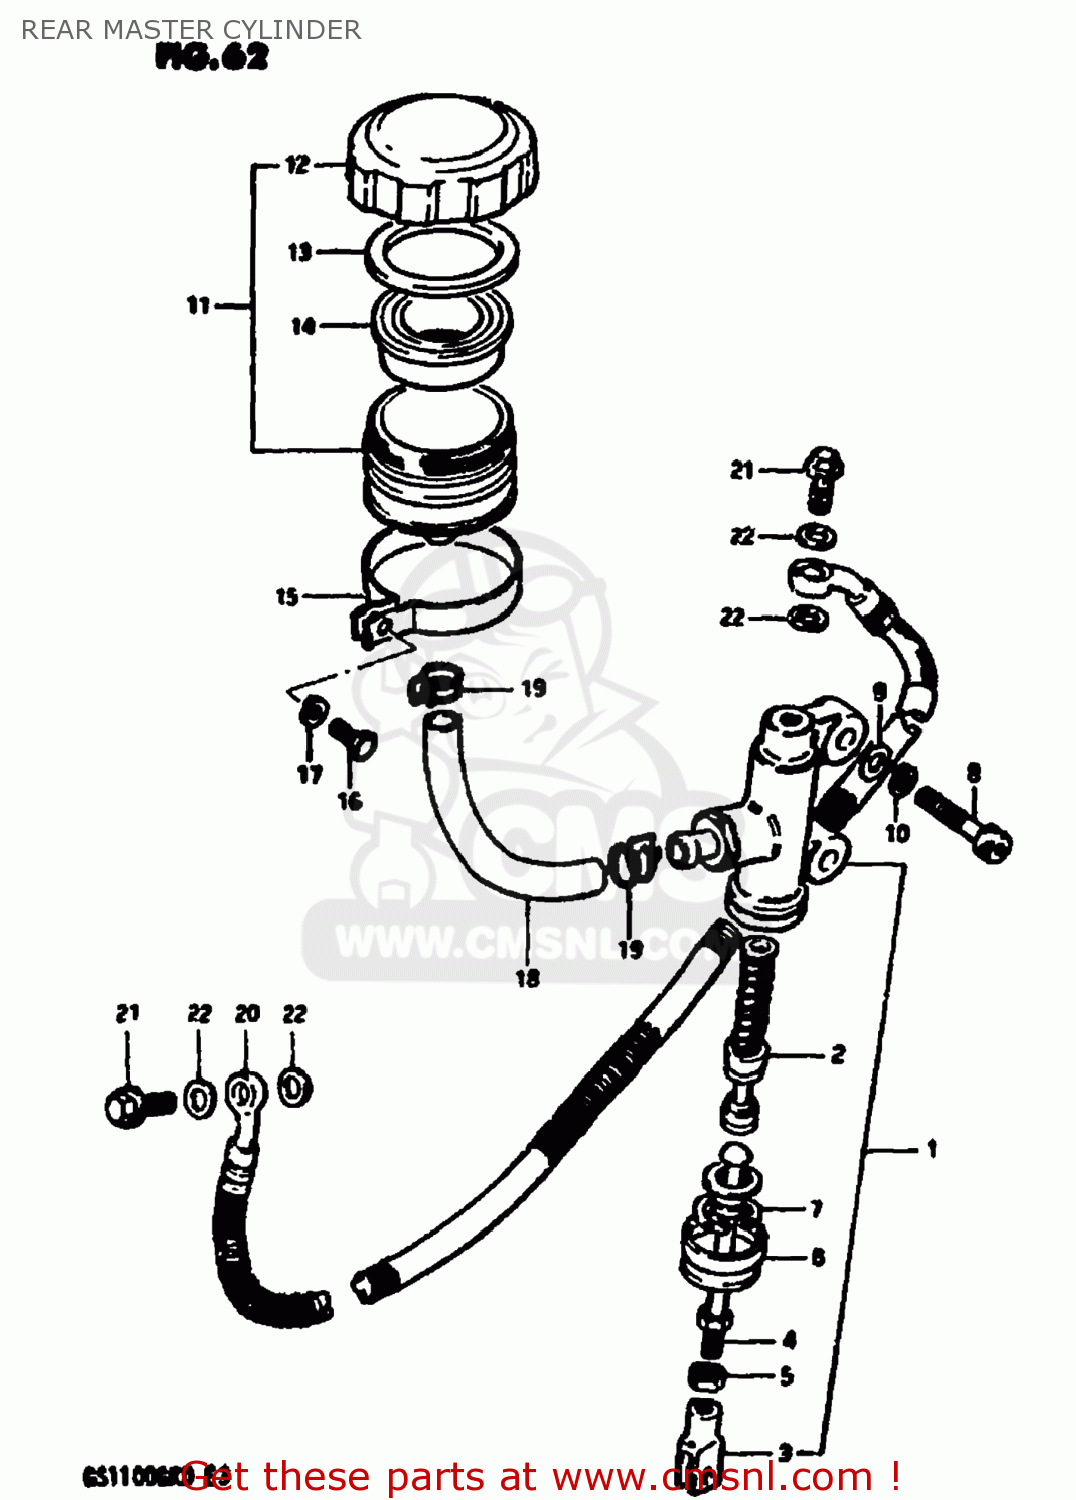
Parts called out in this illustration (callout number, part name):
1	CYLINDER ASSY,RR MASTER
2	PISTON/CUP SET
3	YOKE
4	ROD,REAR MASTER CYLINDER
5	NUT,MASTER CYLINDER
6	BOOT
7	CIRCLIP
8	BOLT
9	WASHER
10	WASHER,LOCK,8.
11	TANK ASSEMBLY,RESERVOIR
12	CAP
13	PLATE,DIAPHRAGM
14	DIAPHRAGM
15	CLAMP
16	BOLT, UPPER
17	LOCK WASHER
18	HOSE,RESERVOIR TANK
19	CLAMP
20	HOSE,REAR BRAKE
21	BOLT,UNION
22	WASHER
